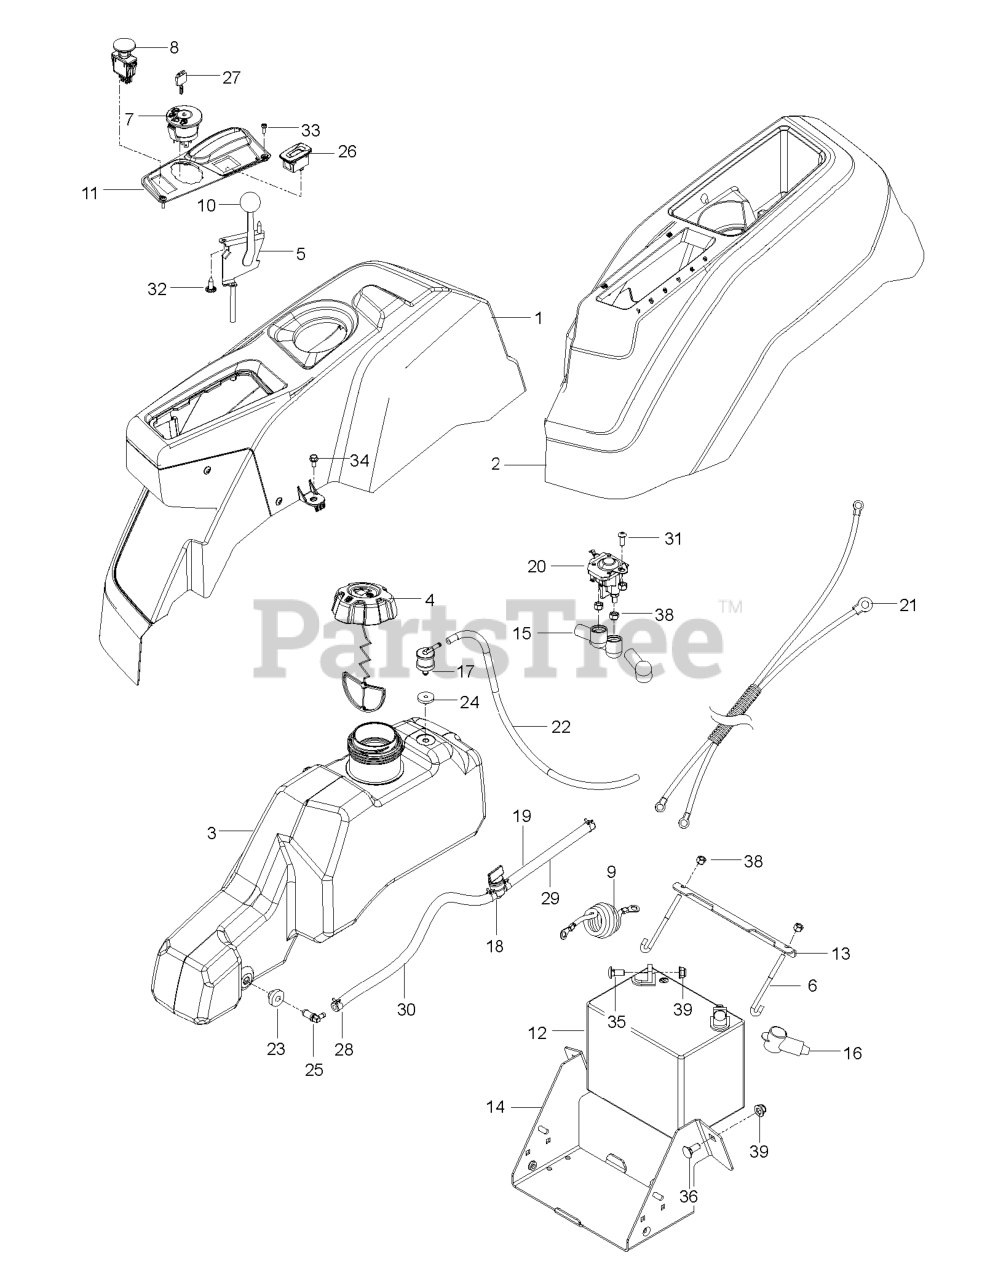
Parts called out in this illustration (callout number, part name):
1	CONSOLE.ASSY.RZ.REFRESH.RH
2	CONSOLE.LH.ASM
3	TANK.ASM3"NECK.NOCAP.NOSHDRZ17
4	CAP ASSY FUEL 3" GRAY
5	CABLE.THROTTLE.37"
6	HOOK.J.BATTERY
7	RP IGNITION SWITCH
8	RP SWITCH.PTO.TERMINAL.STD.RED
9	CABLE BATTERY POS RZ
10	KNOB.ROUND.BALL.BLACK
11	CONTROL.PANEL.RZ.REFRESH.RH
12	BATTERY, 12 V 330 AMP
13	BRACKET.PNT.MOUNT.BATTERY.EDIP
14	BOX.PNT.BATTERY.RZ.EDIP
15	TERMINAL COVER
17	VALVE.FUEL.CHECK
18	FUEL VALVE
19	FUEL.HOSE.SHUT.OFF.ASM.10".3"
20	SOLENOID.STARTER.BRASS.PLUNGER
21	HARNESS.BTTRY.CABLE.RZ.REFRESH
22	HOSE.3/16".VAPOR.LINE.18"LGTH
23	BUSHING OUTLET T
24	GROMMET.ROV.SENTEC
25	STEM FUEL TANK
26	GUAGE.SRVCMNDR.HRMTR.
27	KEY MLD GEN DELTA
28	HOSE CLAMP
29	HOSE.1/4".LOW.PERM.FUEL.LN.10"
30	HOSE 1/4" LOW PERMEATION FUEL
31	SCR 1/4-20 X 5/8 BTN SKT HD ZD
32	SCREW.PAN.HEAD.#10
33	SCREW 6-19X.437
34	SCREW
35	RP BOLT 5/16-18 X3/4 ZN/YEL GR
36	RHSNB 3/8C X 1
37	NUT 3/8-16 HEX FLG NYLOC ZD
38	NUT.1/4-20.HEX.NYLOC.ZD
39	5/16-18 NYLOC FLANGE NUT
